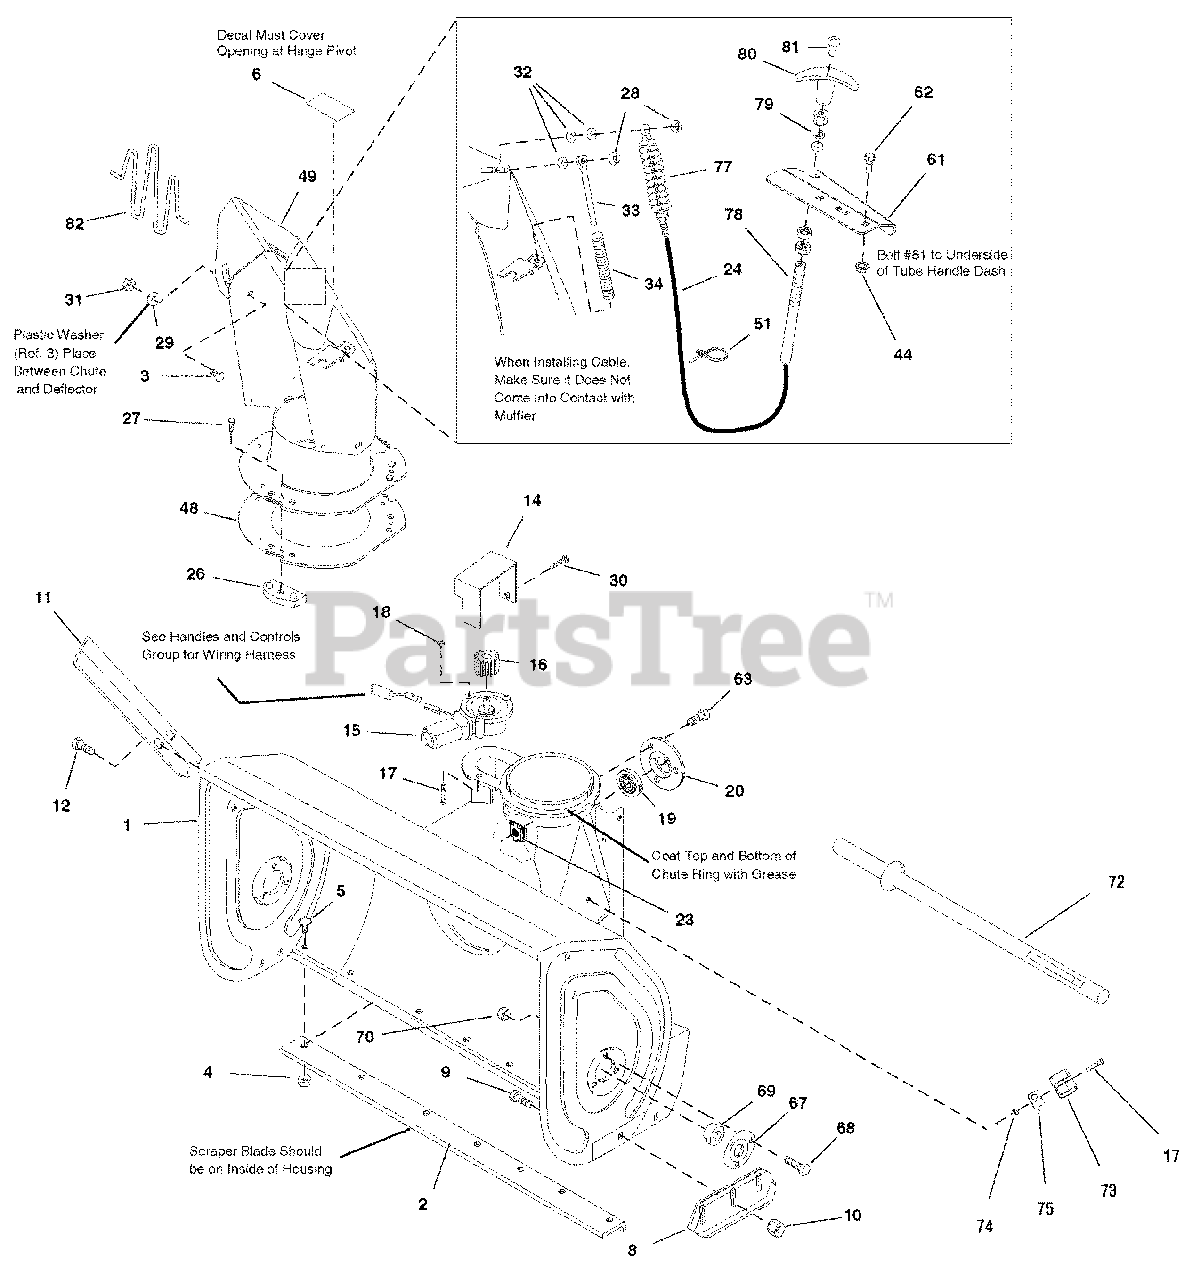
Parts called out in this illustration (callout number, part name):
1	HOUSING ASSEMBLY, 38"
2	BLADE, Scraper 38"
3	CARRIAGE BOLT, 5/16-18 x 3/4, G5
4	NUT, Hex Lock Flange, 5/16-18
5	CARRIAGE BOLT, 5/16-18 x 5/8, G5
6	DECAL, Red Strip
8	SKID SHOE
9	BOLT, Carriage, 3/8-16 X 1
10	NUT, Hex Flange 3/8-16 ESNA
11	CUTTER, Drift
12	SCREW, Hex Washer Head Taptite, 5/16-18 x 3/4
14	COVER, Gear 38"
15	MOTOR, Spout Rotator 38"
16	PINION, 1.417OD .296 Slot, 1-1/4 LG, 16T Powdered Metal
17	CAPSCREW, Hex Washer, #10 x 1-1/4
18	NUT, Hex Whiz Lock Flange, 10-24
19	BEARING, 3/4 ID x 1.78 OD x .61 LG Greased
20	RETAINER, Bearing
23	RETAINER, Nut, 5/16-18 .057/.092
24	CABLE & KNOB ASSEMBLY
26	HOLD DOWN, Chute Black Nylon
27	SCREW, Hex Washer Head Plastite, 10-14 x 5/8
28	NUT, Push Pal, 1/4 DIA Stud Capped
29	WASHER, Nylon, .388 x 1.12 x .03
30	SCREW, Hex Washer Head Taptite, 1/4-20 x 3/8
31	NUT, Hex Flange, 5/16-18 ESNA
32	SPACER
33	ROD, 5/16 DIA 5.88 LG
34	SPRING, Compression
44	NUT, Hex Keps, 1/4-20 Conical Washer
48	GEAR, Chute, 10 OD x 6.65 ID x .105 TH
49	CHUTE ASSEMBLY, 38"
51	TIE, Self Locking, .184 WD 7.31 LG
61	SUPPORT, Cable Tube Handles
62	CAPSCREW, Hex Head 1/4-20 x 3/4, G5
63	SCREW, Hex Whiz Lock Flange, 5/16-18 x 3/4
67	FLANGE, Bearing
68	CAPSCREW, Hex Head, 5/16-18 x 5/8, G5
69	BEARING, Ball, 1.002 ID 2.049 OD 1.09 LG
70	NUT, Hex Whiz Lock Flange, 5/16-18,
72	STICK, Cleanout w/Brush, Snow
73	CLIP, Retainer
74	NUT, Hex Lock, 10-24 with Nylon Insert
75	BLOCK, Universal Pivot
77	BOOT, Bellows
78	COLLET
79	SEAL, Rod
80	KNOB
81	SCREW, 8-32
82	GUARD & SUPPORT ASSEMBLY, Chute
